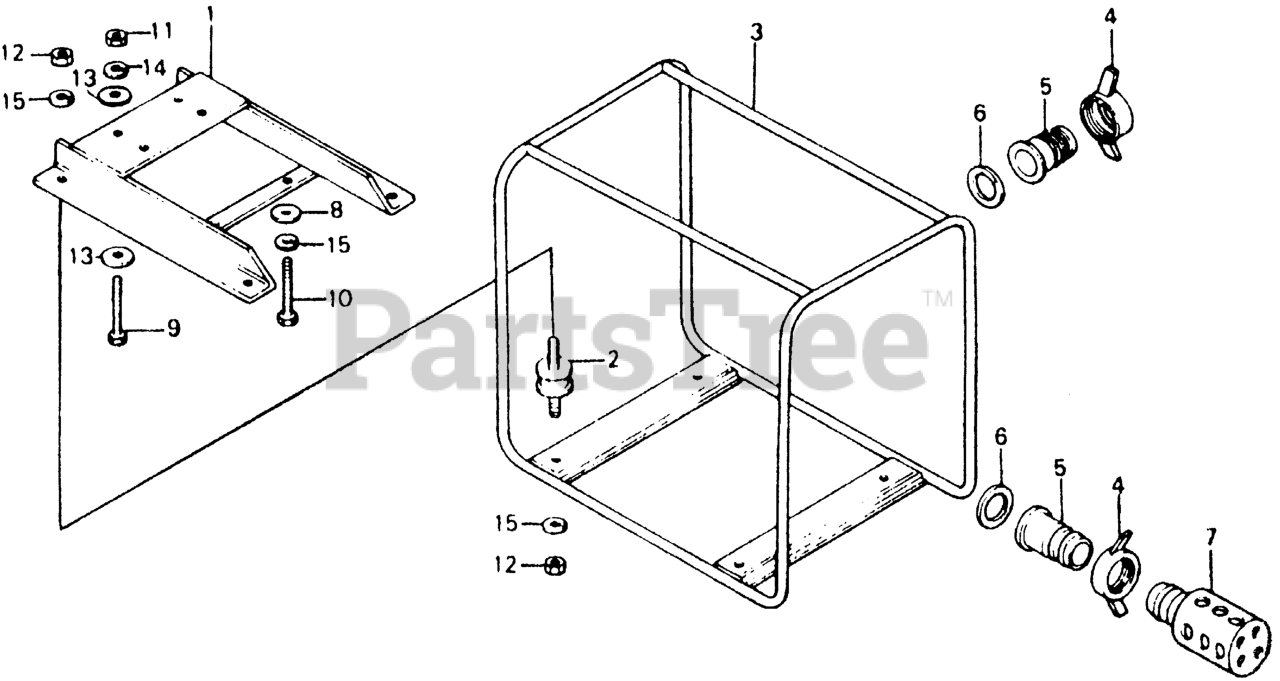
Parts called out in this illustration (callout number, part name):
1	BASE, ENGINE
2	RUBBER, CUSHION (NOT AVAILABLE)
3	PIPE, BASE (NOT AVAILABLE)
4	COUPLING, HOSE
5	JOINT, SUCTION
6	GASKET, HOSE COUPLING
7	STRAINER (NOT AVAILABLE)
9	BOLT, HEX. (10X50)
10	BOLT, HEX. (10X25) Use up to Frame SN 0000290.
11	NUT, HEX. (10MM)
12	NUT, HEX. (10MM)
13	WASHER, PLAIN (10MM)
14	WASHER, SPRING (8MM) Use up to Frame SN 0000290.
15	WASHER, SPRING (8MM) Use up to Frame SN 0000290.
